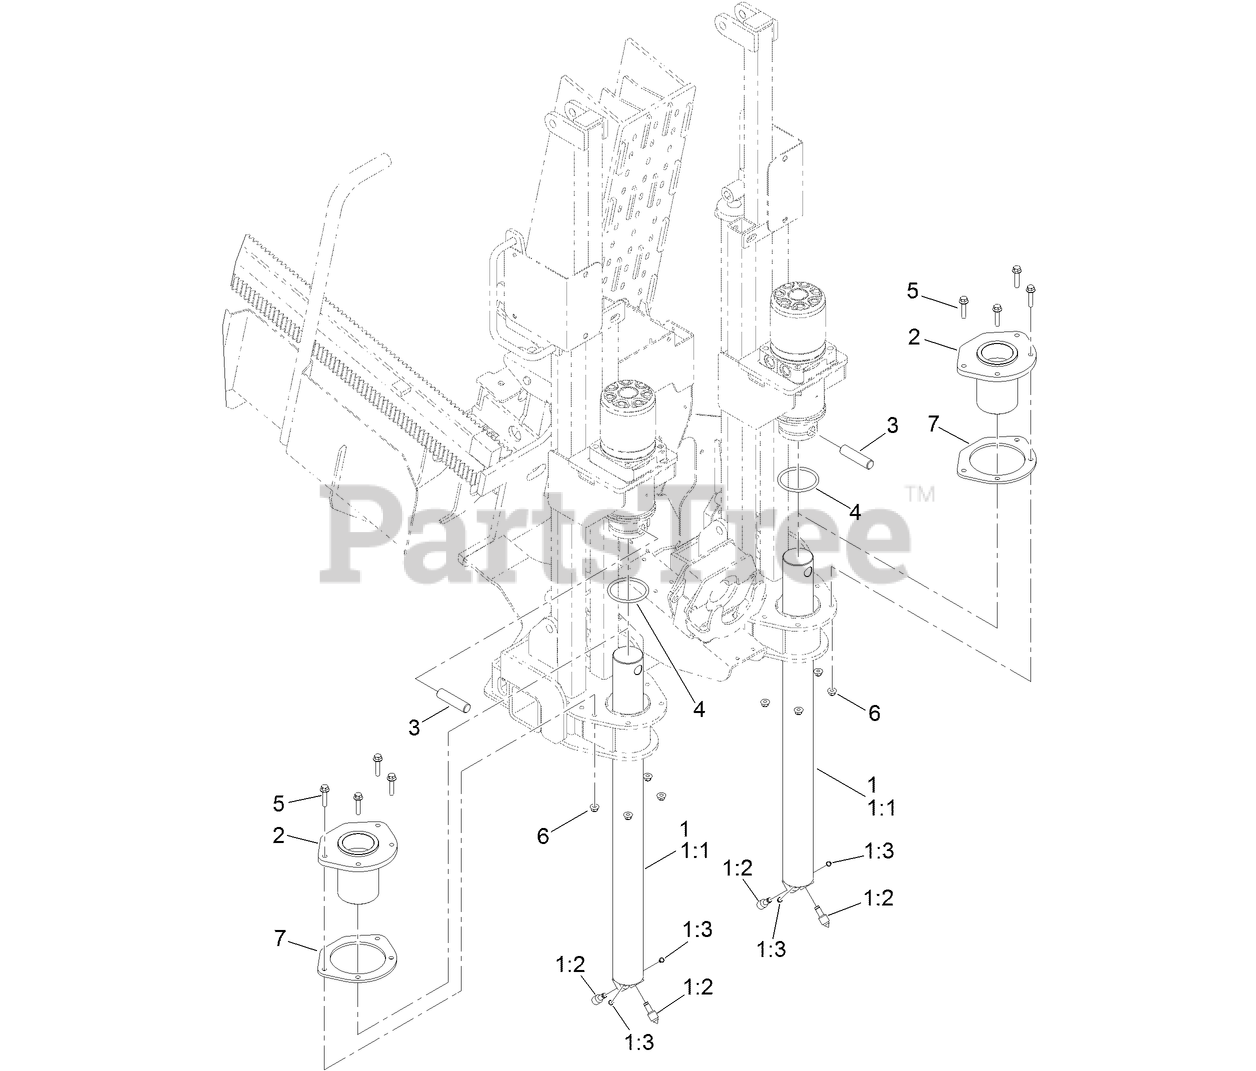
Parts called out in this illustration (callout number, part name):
1	HD ROCK STAKE ASM
1:1	STAKE-ROCK, HD
1:2	BIT-BULLET, MINI
1:3	RING-SNAP
2	GUIDE-STAKE
3	PIN-STAKE
4	O-RING
5	SCREW-HHF
6	NUT-HF, NI
7	PLATE-SPACER, ROCK STAKE
